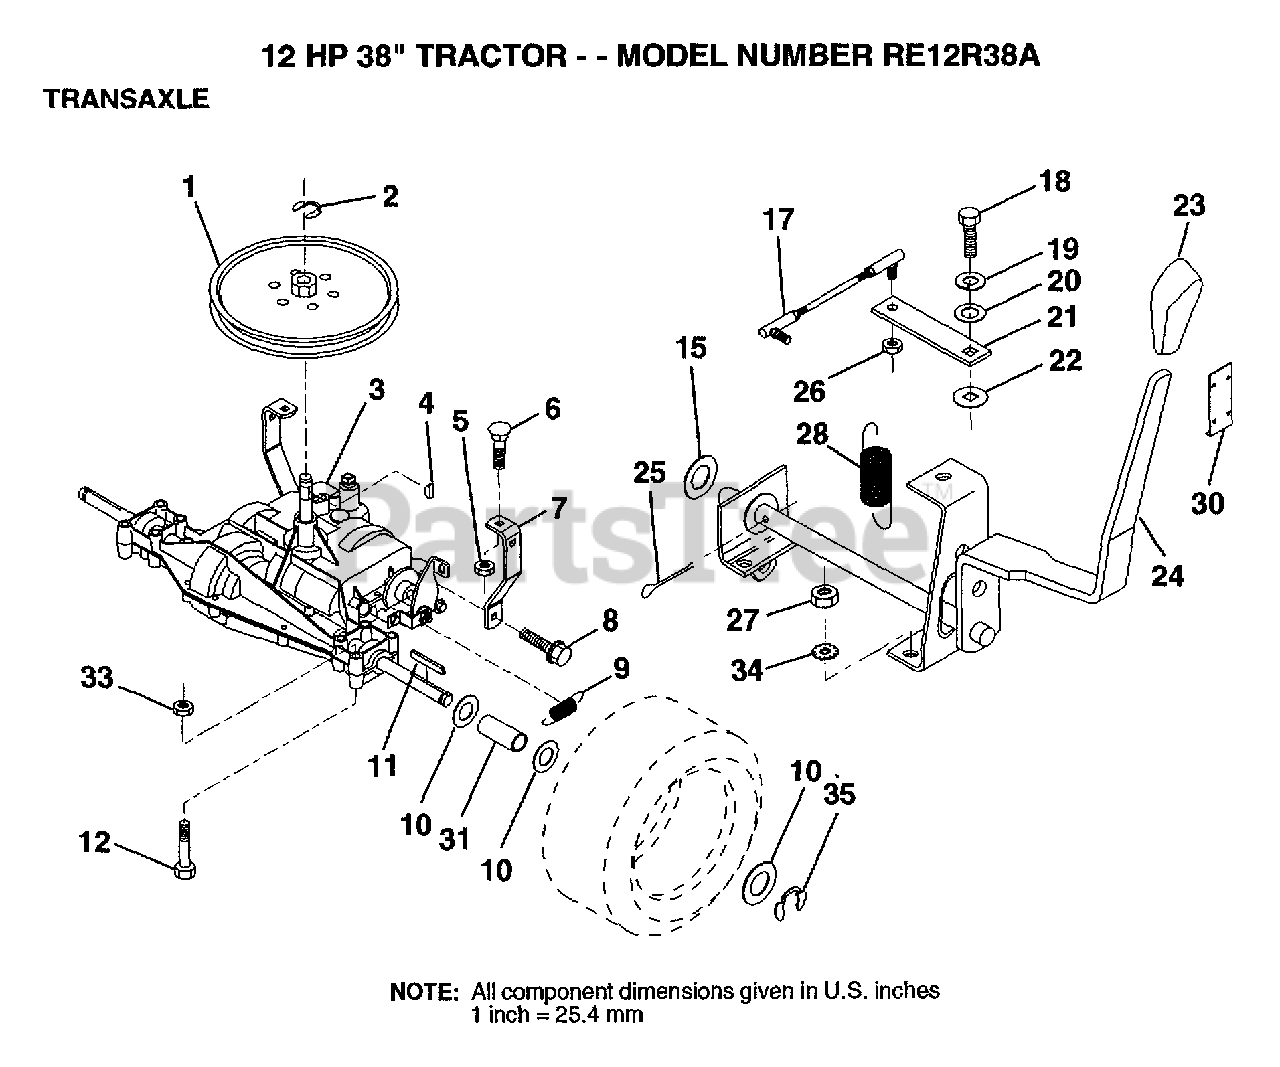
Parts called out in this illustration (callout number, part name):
1	PULLEY
6	BOLT
7	STRAP,TORQUE
8	SCREW
10	WASHER (2513009)
11	SQUARE KEY
12	BOLT
17	LINK,SHIFT
19	LOCKWASHER
20	WASHER LT
22	WASH-SHFT PLT LT
25	PIN COTTER 1/8
26	NUT.LOCK.5/16-24
28	"SPRING,EXT"
34	LOCKWASHER.5/16.E
35	E-RING LT
